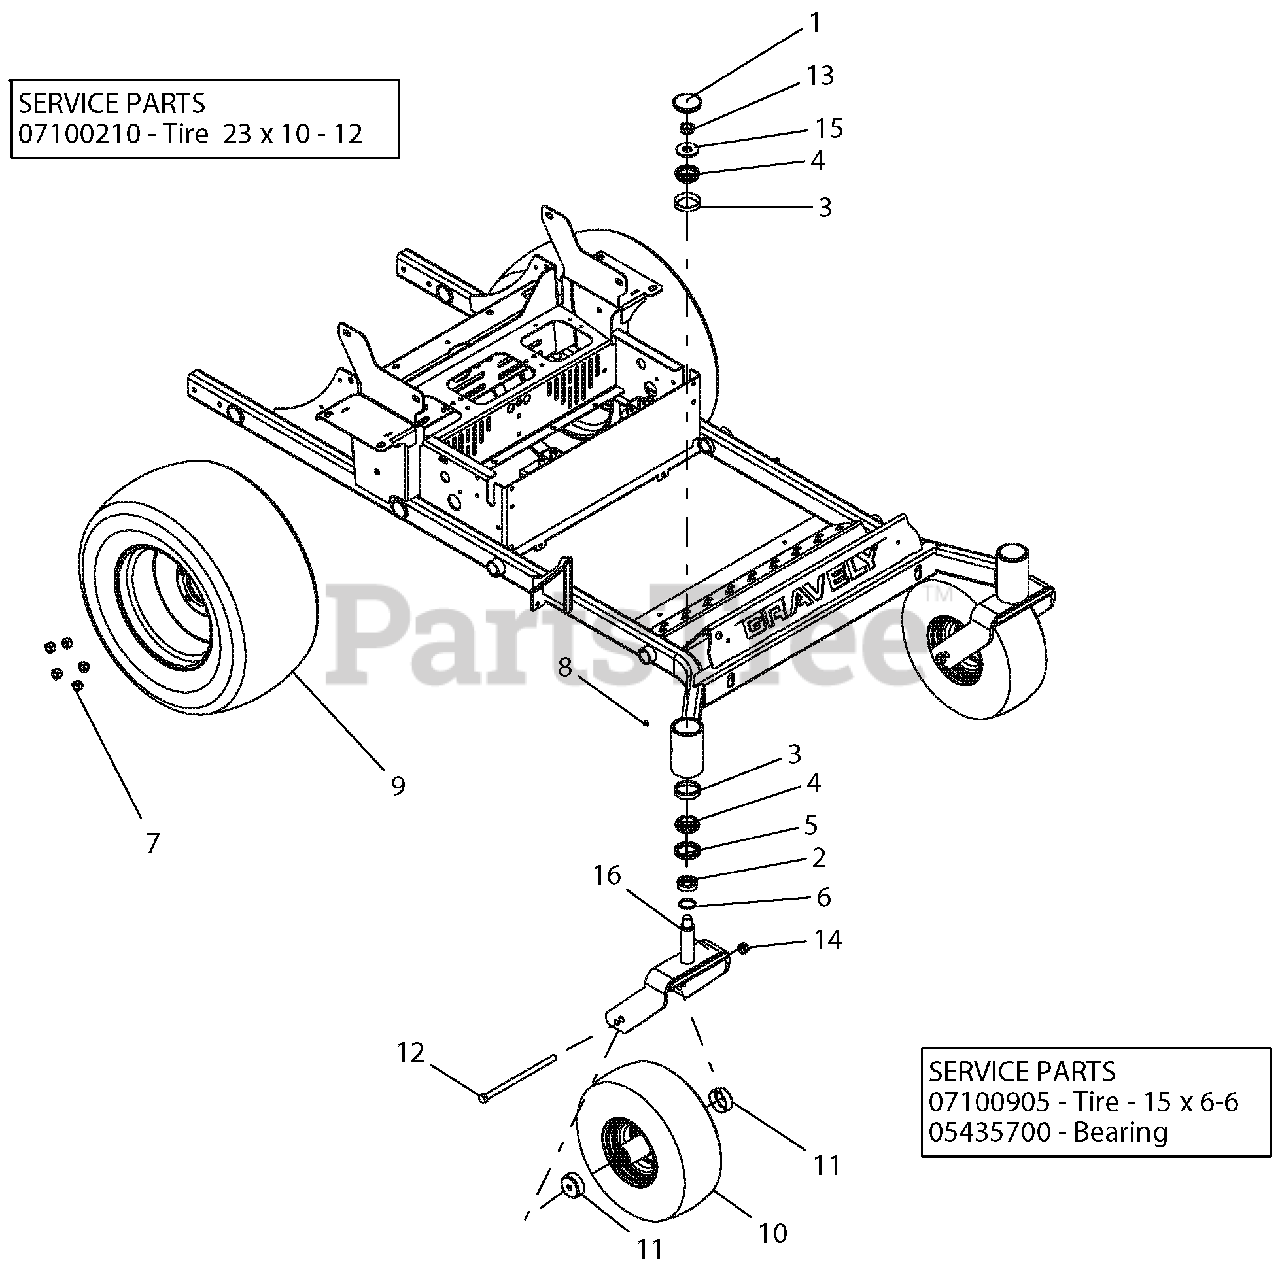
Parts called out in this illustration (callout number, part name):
1	CAP, DUST
2	SPCR, FRONT CASTER FORK
3	BRG, CUP 2.328 X .465
4	BRG, CONE 1.250 X .660
5	SEAL, OIL 1.75 X 2.332 X .312
6	O-RING, .139 W X 1.234 ID
7	NUT, LUG .500-13
8	PLUG, .250-28 X .185 HEX HEAD
9	ASSM TIREWHEEL, 23X10-12
10	TIRE/WHEEL, 15 X 6.00-6 SMOOTH
11	SHIELD, WHEEL BEARING
12	BLT-HEX .50-13X9.00 GR5 YWZC
13	@NUT-LK-CTR-JAM .75-16 YWZC
14	NUT, LK-TOP-FLG .50-13 YWZC
15	WSHR-FL-STL.812X2.00X.148YWZC
16	WMT, CASTER FORK - RED
